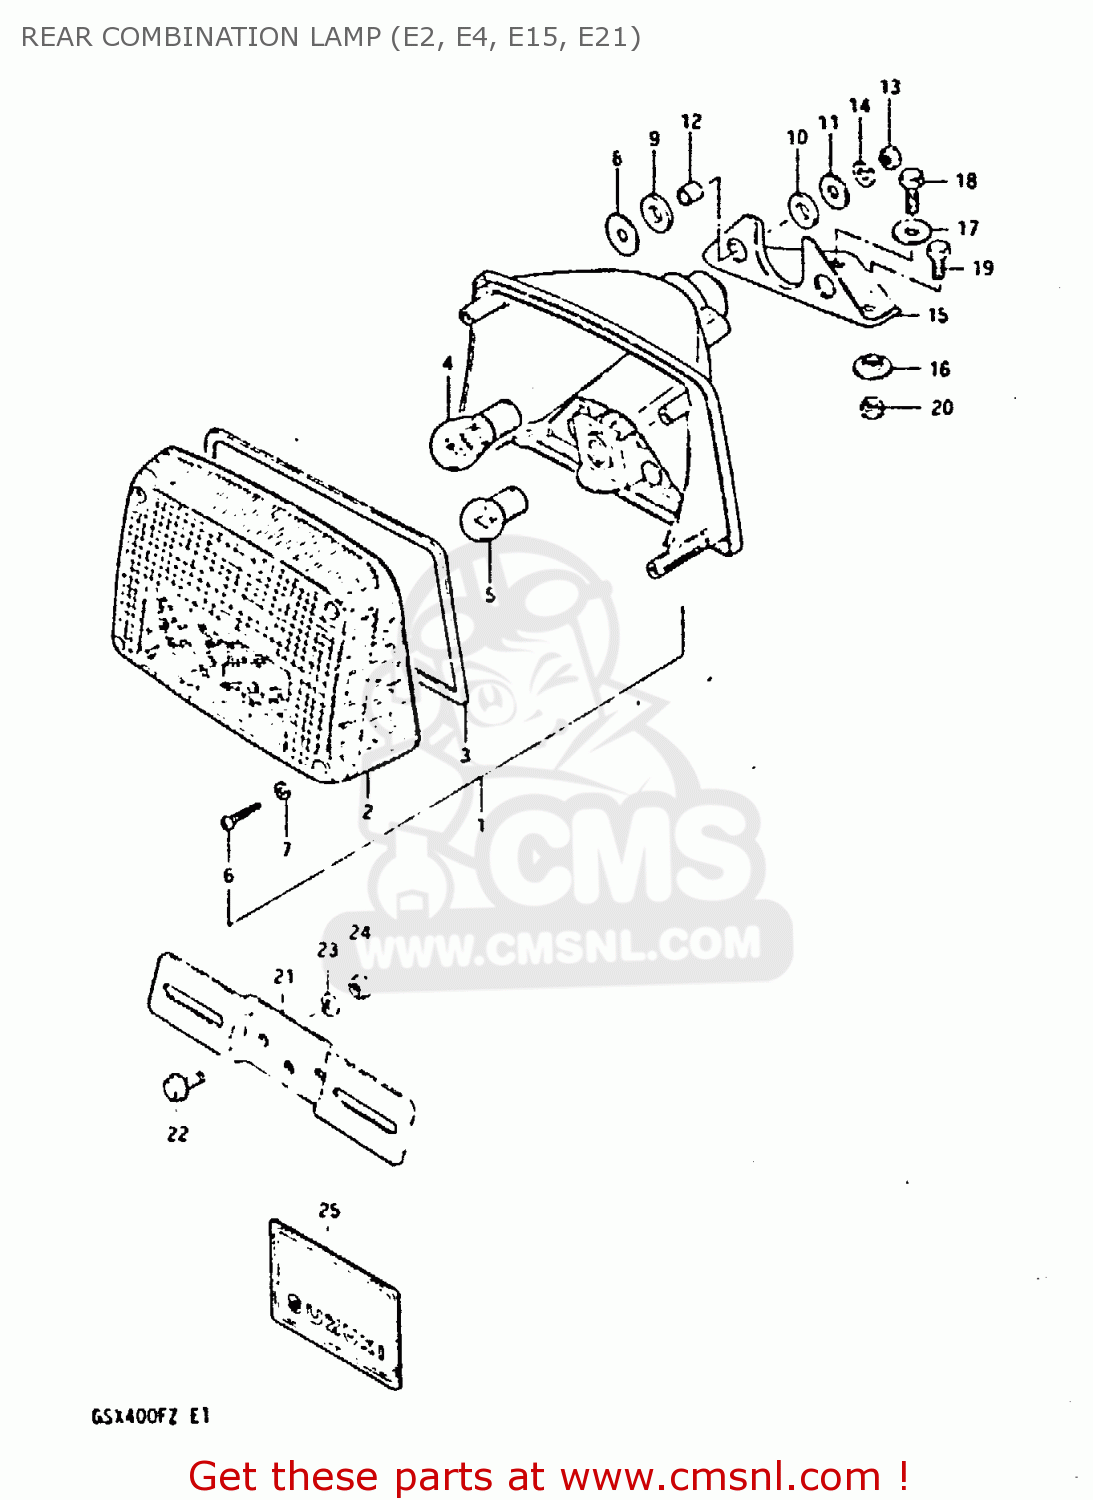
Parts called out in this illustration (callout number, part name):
1	LAMP, REAR COMBINATION
2	LENS
3	GASKET (NAS)
4	BULB 12V21/5W
5	BULB
6	SCREW,REAR COMBINATION LAMP
7	GASKET (NAS)
8	WASHER
9	CUSHION
10	CUSHION
11	WASHER(6,5X22X1.6)
12	SPACER(6.1X9X7.5)
13	NUT
14	LOCK WASHER
15	BRACKET,RR COMBINATION LAMP
16	WASHER
17	WASHER
18	BOLT
19	BOLT, UPPER
20	NUT 6MM
21	BRACKET, LICENSE PLATE
22	BOLT
23	LOCK WASHER
24	NUT
